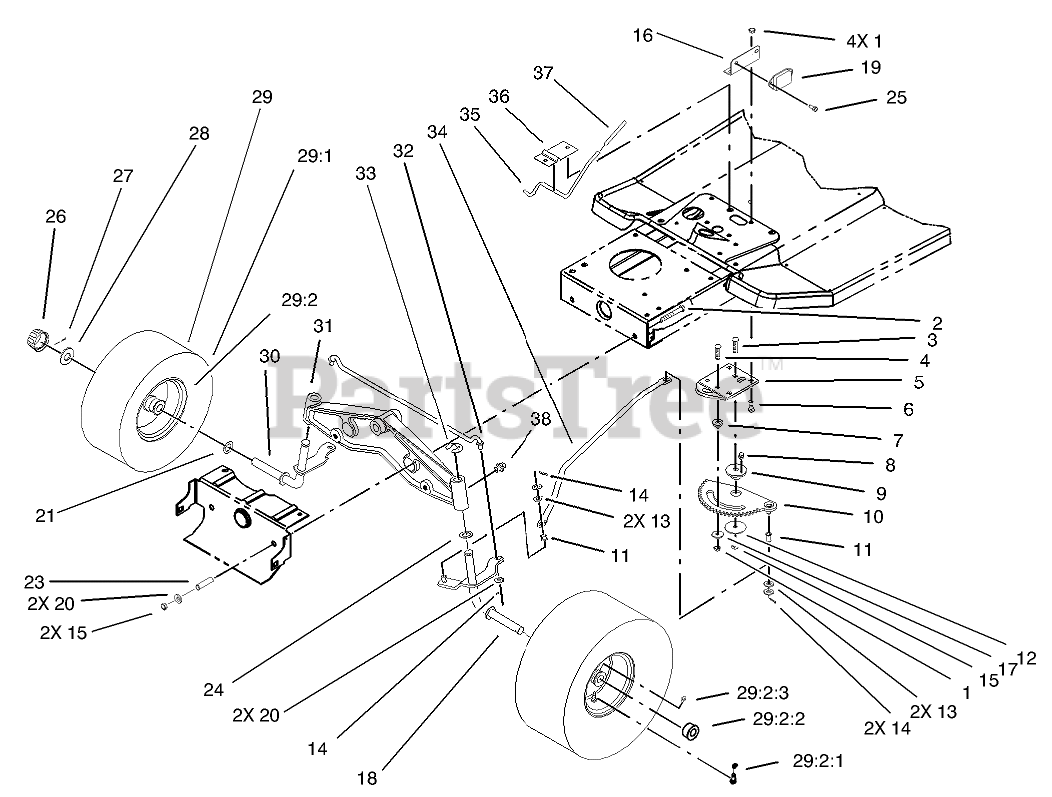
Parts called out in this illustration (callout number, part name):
1	NUT-LOCK, NI
2	SCREW-HH
3	SCREW-CARR
4	SCREW-CARR
5	BRACKET-RACK, STEERING
6	BOLT-CARR
7	SPACER-RACK, STEERING
8	FITTING-GREASE
9	BUSHING-ECCENTRIC
10	RACK-STEERING
11	BUSHING-FLANGED, NYLON
12	WASHER-BEARING
13	WASHER-FLAT
14	PIN-COTTER
15	NUT-LOCK, NI
16	BRACKET-MODULE
17	WASHER-PIVOT
18	LH SPINDLE ASM
19	MODULE
20	WASHER-FLAT
21	WASHER-THRUST
23	SPACER
24	WASHER-THRUST
25	SCREW-HWH
26	CAP-HUB
27	PIN-COTTER
28	WASHER-PLAIN
29	FRONT WHEEL & TIRE ASM
29:2	RIM ASM
29:2:1	STEM-VALVE
29:2:2	BEARING-WHEEL
29:2:3	FITTING-GREASE
30	RH SPINDLE ASM
31	AXLE-FRONT
32	TIE ROD-STEERING
33	E-RING
34	LINK-DRAG
35	ROD-BRAKE, PARKING
36	BRACKET-PARKING BRAKE
37	GRIP-BRAKE, PARKING
38	FITTING-GREASE
